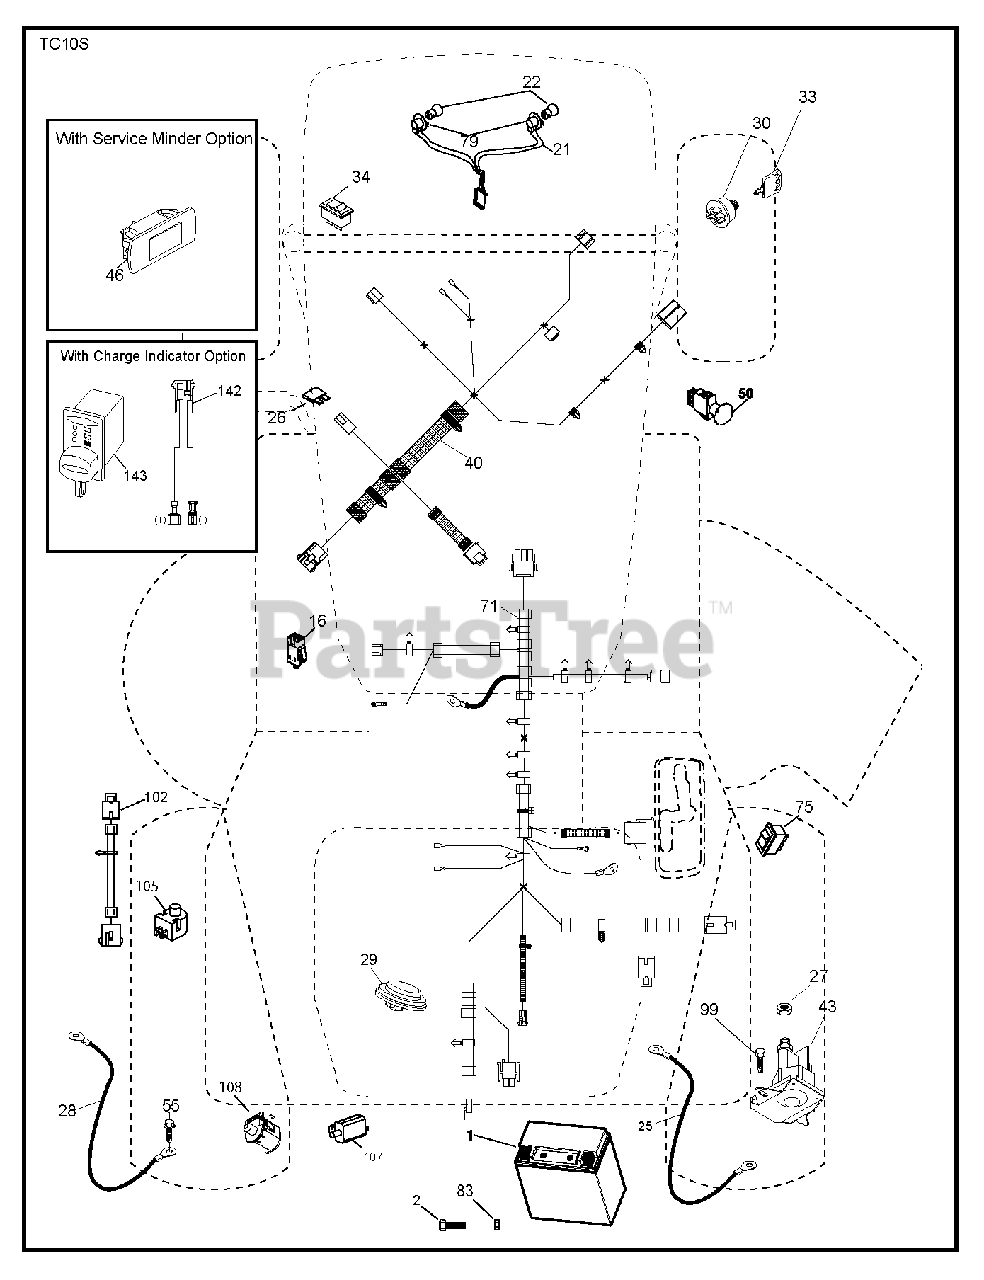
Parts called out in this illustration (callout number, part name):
1	BATTERY BATTERY 14AH 12V LEOC
2	SCREW.HEX.HEAD.CAP.M6 X1.12W
16	SWITCH INTERLOOK PUSH-IN
21	HARNESS.LIGHT W/4152J BULBS
25	CABLE CABLE.BLACK.20.8AWG.M6.C
26	FUSE 20AMP
27	NUT
28	SUPPORT SUPPORT.SSST.REAR.FRAM
29	SWITCH.SEAT.DELTA.OPC.
30	SWITCH.IGN.DELTA.W.LGH.ROS
33	KEY.CHAIN.BLISTER.PACK.GEN.INT
40	HARNESS.DASH.ELECT.SRD.BAT.CHR
43	SOLENOID.W/BRASS.PLUNGER
46	RP GUAGE.SRVCMNDR.HRMTR.
50	RB PTO.SWITCH.8 TERMINAL.BLACK
55	SCREW 5/16"
71	HARNESS.CH.TCRD.HYD.TWIN.ELD.
75	SWITCH.BAG.DUMP
79	BULB HOLDER ASM.
83	NUT NUT SQUARE
99	SCREW
102	HARNESS ASSY
105	REVERSE SWITCH
107	.WITCH.FULL BAGGER.INDICATOR
108	SWITCH.SNAPMOUNT.NC
142	CHARGE.PORT.PIGTAIL HARNESS
143	CHARGE.PORT
